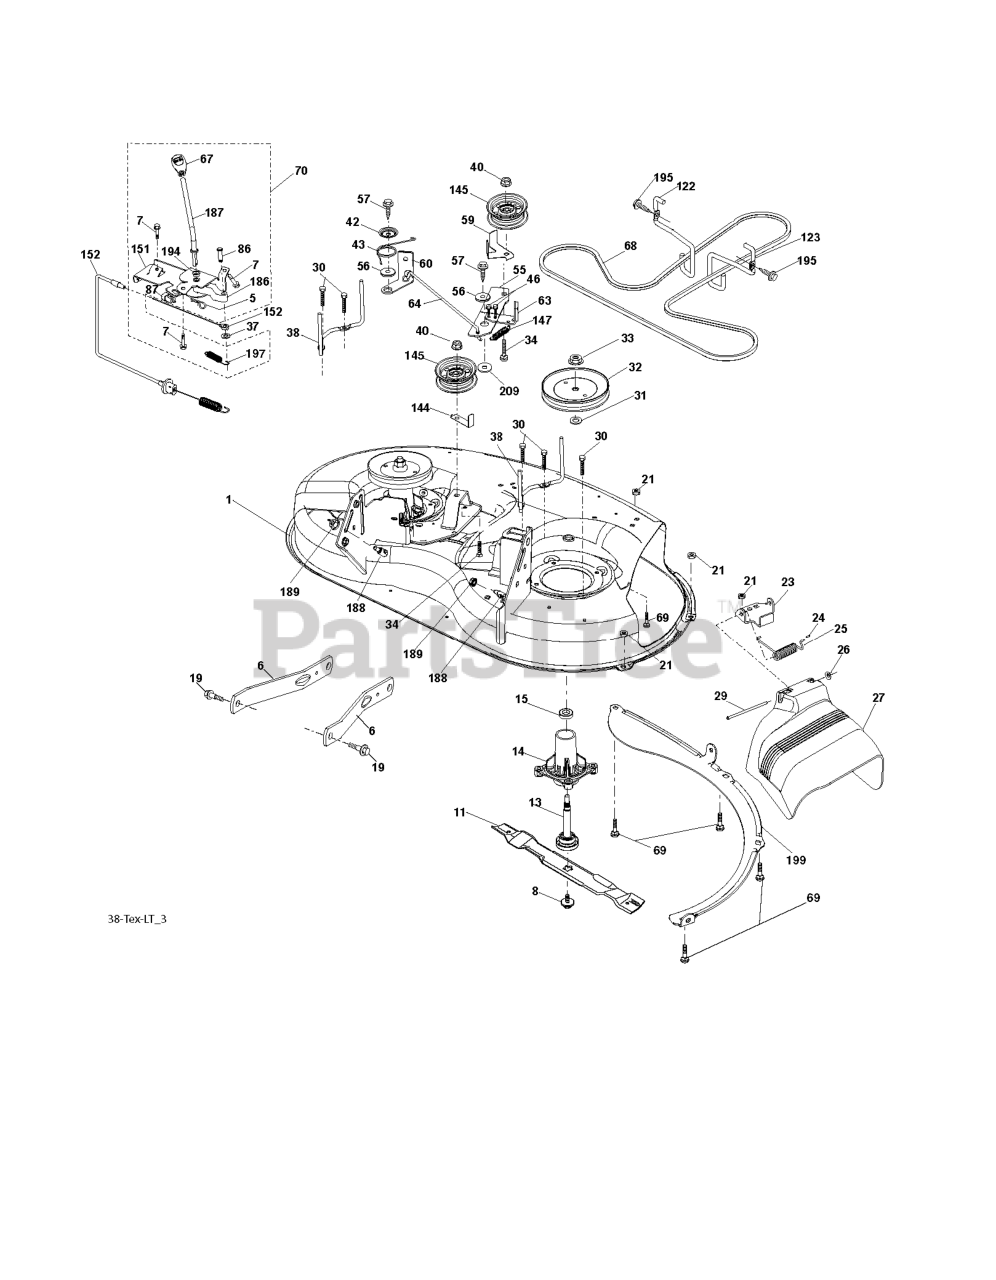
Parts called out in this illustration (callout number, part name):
1	HOUSING
5	RETAINER-SPRNG RB
6	ARM.SUSPENSION.MOWER.R
7	SCREW
8	BOLT.WASHER.ASM.7/16-2
11	BLADE 38" PREMIUM
13	SHAFT.ASM.MDRL.N/GREASE.38
14	RP.HOUSING.MANDREL.4PT.
19	BOLT.SHOULDER
21	LOCKNUT
23	BRKT.DEFLECTOR.38"2005+
24	CAP-SLEEVE LT
25	SPRING.TORSION.DEFLECT
26	NUT PUSH M
27	SHIELD.DEFLECTOR.MWR.38-7/97CM
29	ROD.HINGE
30	SCREW, WASHER HEAD
31	WASHER.SPACER.MANDREL
32	PULLEY.MANDREL.5.0.PD.38"
33	NUT.FLANGE.LOCK.TOP
34	BOLT.3/8-16X1.50
37	WASHER
38	KEEPER BELT LH MANDREL
40	NUT LOCK FLG 3/8-16 UNC
42	SPRING.TORSION.BRAKE
43	SRPING.TORSION.RETAINE
46	SCREW.1/4-20X5/8
56	SPACER.RETAINER
57	SCREW 3/8-16X1
59	GUARD, BELT
60	ARM BRAKE MOWER RH 38"
63	RP ARM.BRAKE.MOWER.38"LH.TEX
64	LINK BRAKE
67	HANDLE.CLUTCH.CABLE.LT
69	BOLT
70	CLUTCH.ASM.MANUAL.LT.PRED
86	PIN ATTACHMENT CABLE
87	SWITCH.INTRLCK.CLUTCH.
122	KEEPER BELT ENGINE LH
123	KEEPER BELT RH
144	KEEPER BELT
145	PULLEY.IDLER.48"PRIMARY
147	SPRING RETURN
151	BRACKET.CLUTCH CBL.PRED LT
152	CLUTCH CABLE
186	ARM ACTUATOR
187	LEVER.CONTROL.CL.CABLE.PRED LT
188	STUD.FASTNER.W/ANTI-ROTATE
189	NUT LOCK HEX FLANGE 5/16-18
194	BEARING.CONTROL.LEVER.CLUTCH
195	SCREW, 3/8-16X3/4
197	SPRING.PLUNGER.ACTUATOR
199	BAFFLE.VORTEX.FRONT.38"
209	WASHER 12/32X2X10GA
210	STAND, BRAKE
211	ARM, BRAKE
212	GUARD BRAKE
213	BRAKE.SPACER.38".DECK
214	BOLT/WASHER ASM 5/16-18
215	NUT.71038.31-18.HEX.NYLOCK
